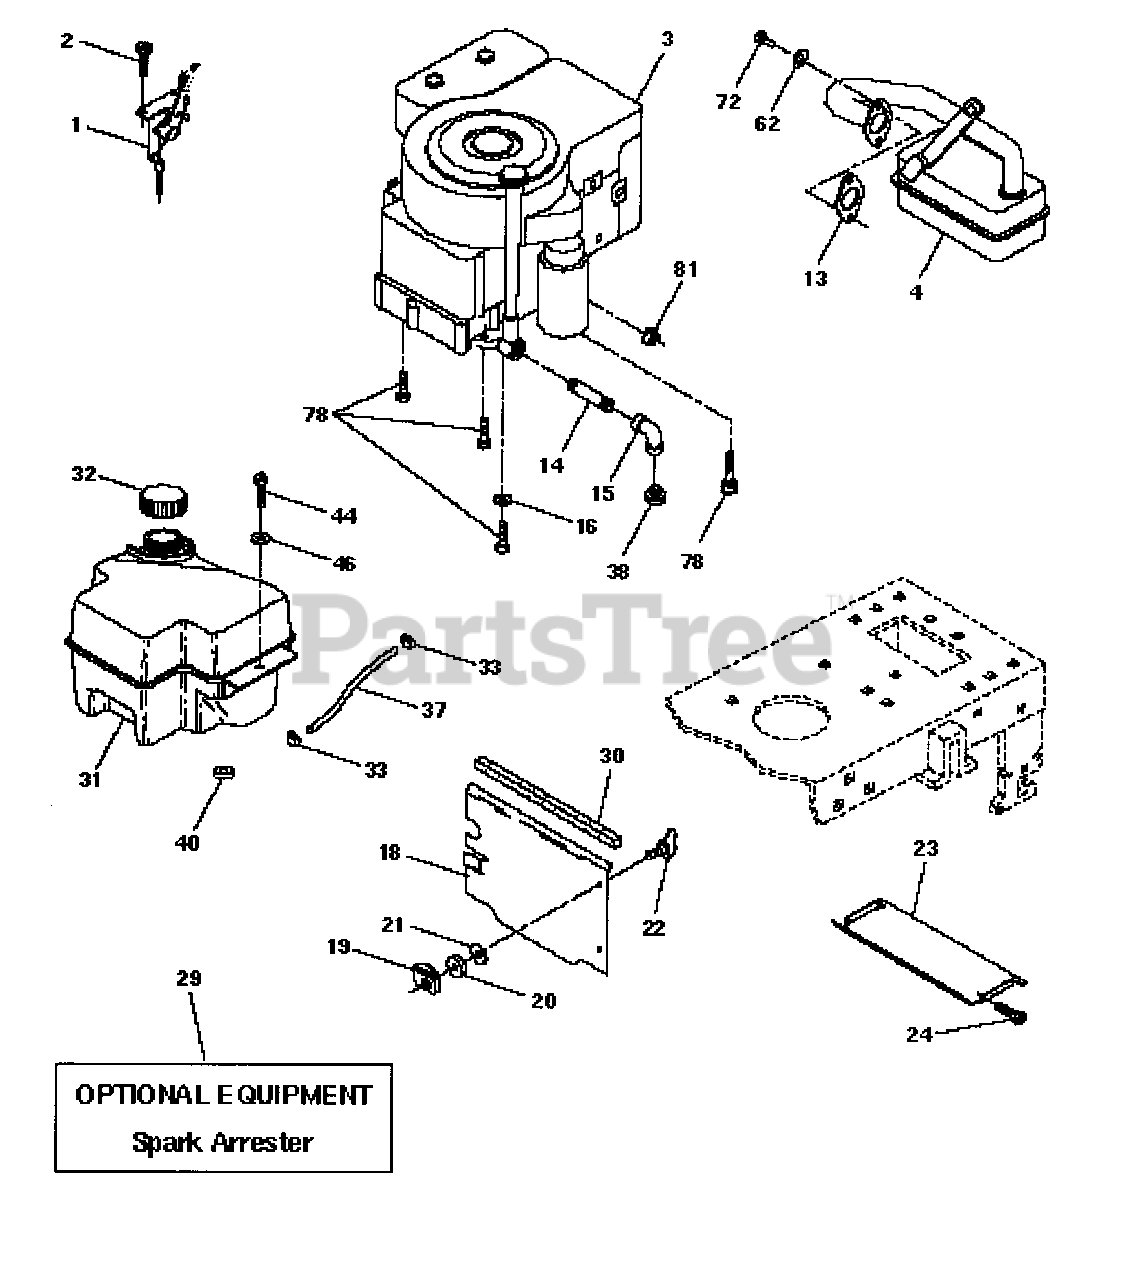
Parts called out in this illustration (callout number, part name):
1	Control Th/ch RH Blk Tee Eec
2	Screw Hex Thd Cut 1/4-20x5/8 T
4	Muffler LT B&S 12/12.5 HP
13	Gasket Eng 1 313 Id Tin Plated
14	Nipple Pipe 3/8 Npt X 3"
15	Elbow Std 90 Degree 3/8-18 Npt
16	Washer Lock Ext Tooth 3/8
18	Shield Heat LT
19	Receptacle 1/4 Turn dacrotized
20	Retainer 1/4 Turn 365 OD x .222 ID
21	Washer 9/32 x 5/8 x 16 Ga
22	Stud 1/4 Turn
23	Shield Heat Browning LT/YT
24	Screw Tap Hex #10-24unc X 1/2
29	Kit Spark Arrestor 1 25
30	Pinch Weld Hood Black 2.00
31	Tank Fuel Front 2.00
32	Cap Asm Fuel W/sym Vented
33	Clamp Hose Blk
37	Line Fuel 9 20"
38	Plug Oil Drain
40	Bushing Snap Nyl Blk Fuel Line
44	Screw Hexwsh Thdrol 1/4-20x3/4
46	Washer 9/32 X 7/8 X 16ga
62	Washer Lock Hvy Hlcl Spr 5/16
72	Screw Hexhd Cap 5/16-18x3/4
78	Screw Thdrol 3/8-16x1-1/4 TYTT
81	Nut Keps Hex 1/4-20 UNC
